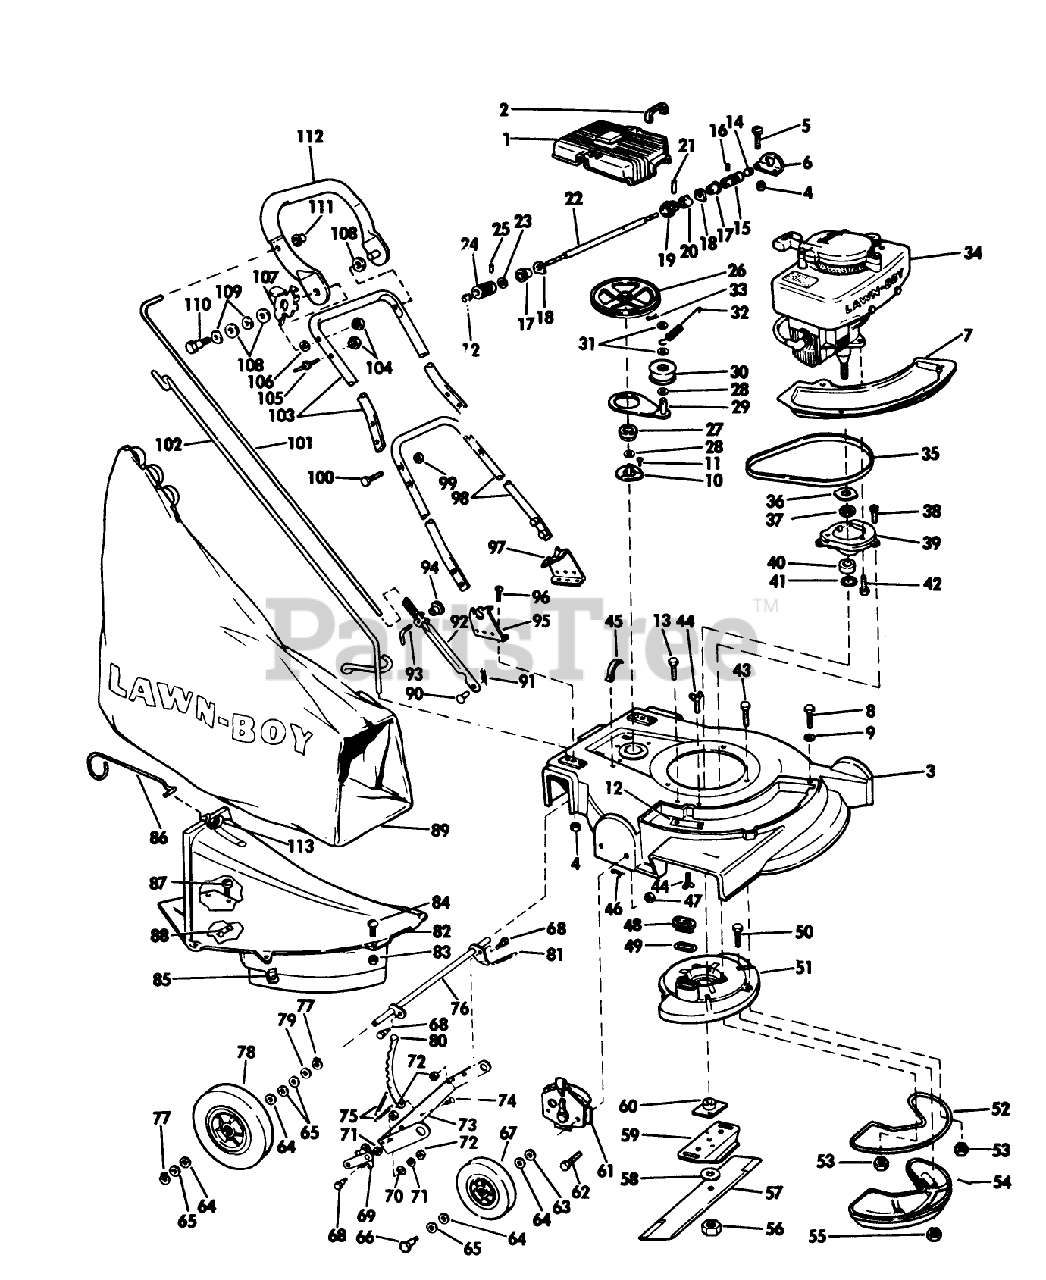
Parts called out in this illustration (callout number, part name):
5	SCREW
8	SCREW SEMS TRM HEX HD
14	GREASE PLUG
26	PULLEY&OILER FELT (13)
35	BELT
42	BOLT F
43	SCREW
47	NUT
48	SLEEVE
49	GASKET S
53	NUT
55	LOCKNUT E
56	NUT-BLADE
58	WASHER
60	PLATE AND COLLAR ASM
63	WASHER WROUGHT
64	WASHER
65	SPACER
66	BOLT WHEEL
67	WHEEL & TIRE KIT
68	BOLT RB&W
71	WASHER S
72	STOP NUT
77	RETAINING RING
79	WASHER
81	SPRING
82	Skirt Assembly
83	NUT S
85	SPEED NUT ARDEN
89	89802 LB WHOLE GOODS
96	SCREW S
100	SCREW
108	WASHER M
110	BOLT PIONEER
